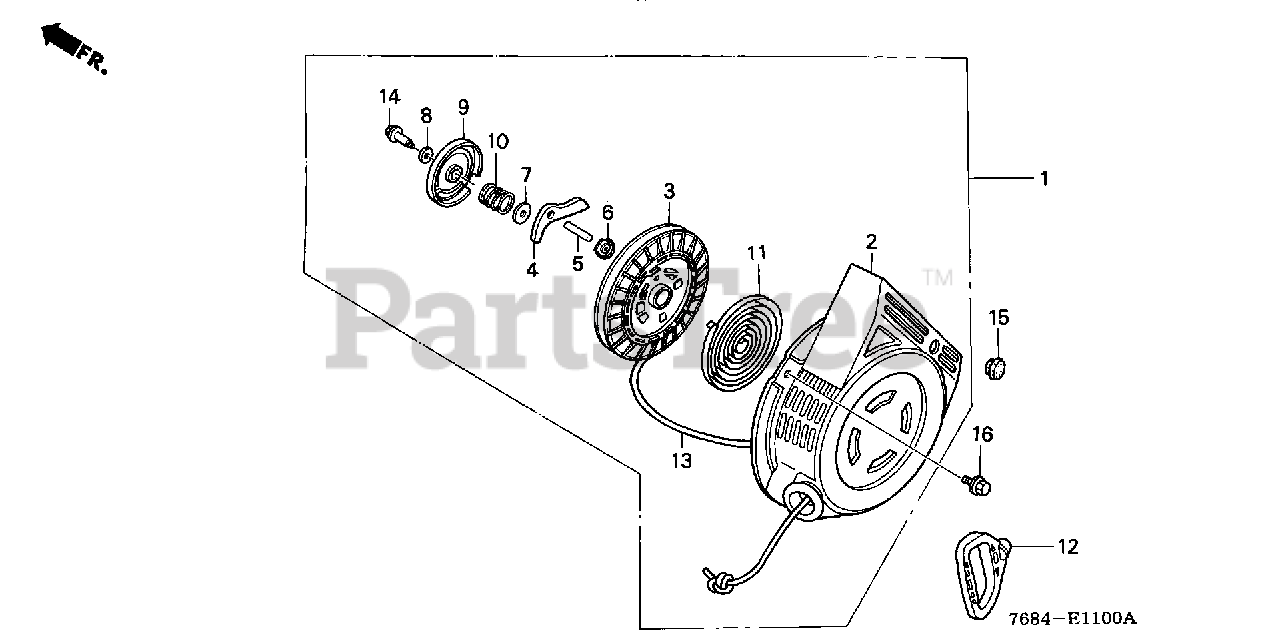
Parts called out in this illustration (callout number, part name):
1	STARTER ASSY., RECOIL *R8* (BRIGHT RED)
2	CASE, STARTER *R8* (BRIGHT RED) (NOT AVAILABLE)
3	REEL, STARTER
4	RATCHET, STARTER
5	SHAFT, RATCHET (NOT AVAILABLE)
6	PLATE, GUIDE
7	PLATE A, FRICTION
8	PLATE B, FRICTION
9	COVER, STARTER REEL
10	SPRING, FRICTION
11	SPRING, RETURN
12	GRIP, STARTER
13	ROPE, RECOIL STARTER
14	BOLT, REEL COVER
15	GROMMET B, CONTROL WIRE (16MM)
16	BOLT, FLANGE (6X8)
